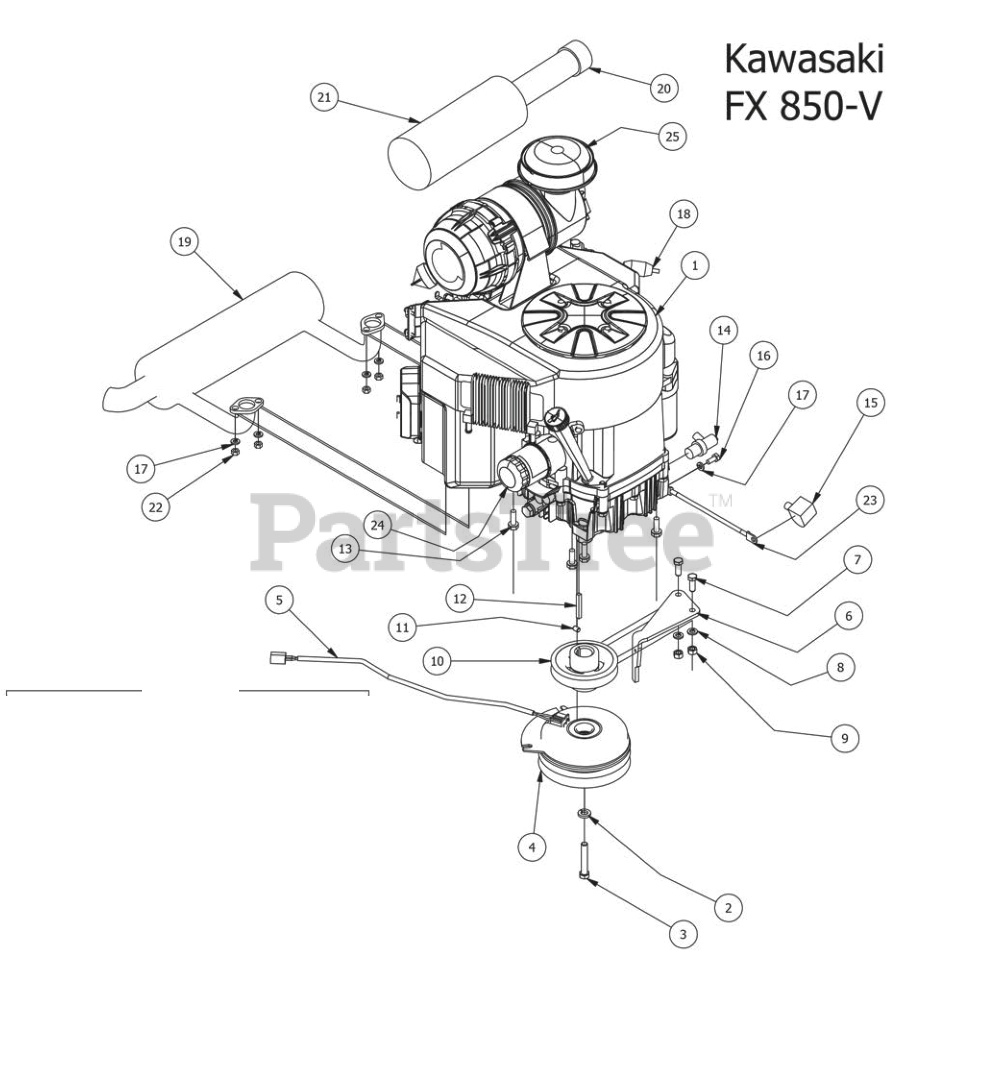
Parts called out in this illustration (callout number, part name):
1	Kawasaki Engine FX-850-V-CS09R
2	7/16" Lock Washer
3	7/16" x 2 1/2" Hex Bolt
4	Clutch Assembly
5	Clutch Pigtail
6	PTO Engager Holder
7	3/8" x 1" Hex Bolt
8	3/8" Lock Washer
9	3/8" Hex Nut
10	4 3/4 Motor Pulley
11	3/8" Set Screw
12	1/4 x 2 Square key Stock
13	3/8 x 1 1/8 bolt
15	Black Boot For ground cable
16	M8x1.20x20MM Hex head bolt
17	5/16" Lock Washer
18	Universal inline Fuel Filter
19	Kawasaki Exhaust
20	Canister Air Filter- Inner
21	Canister Air Filter-Outer
22	M8-1.25 Zinc Nut
23	Starter to chassis cable
24	Kawsaki Oil Filter
25	Kawasaki Rain Cap
